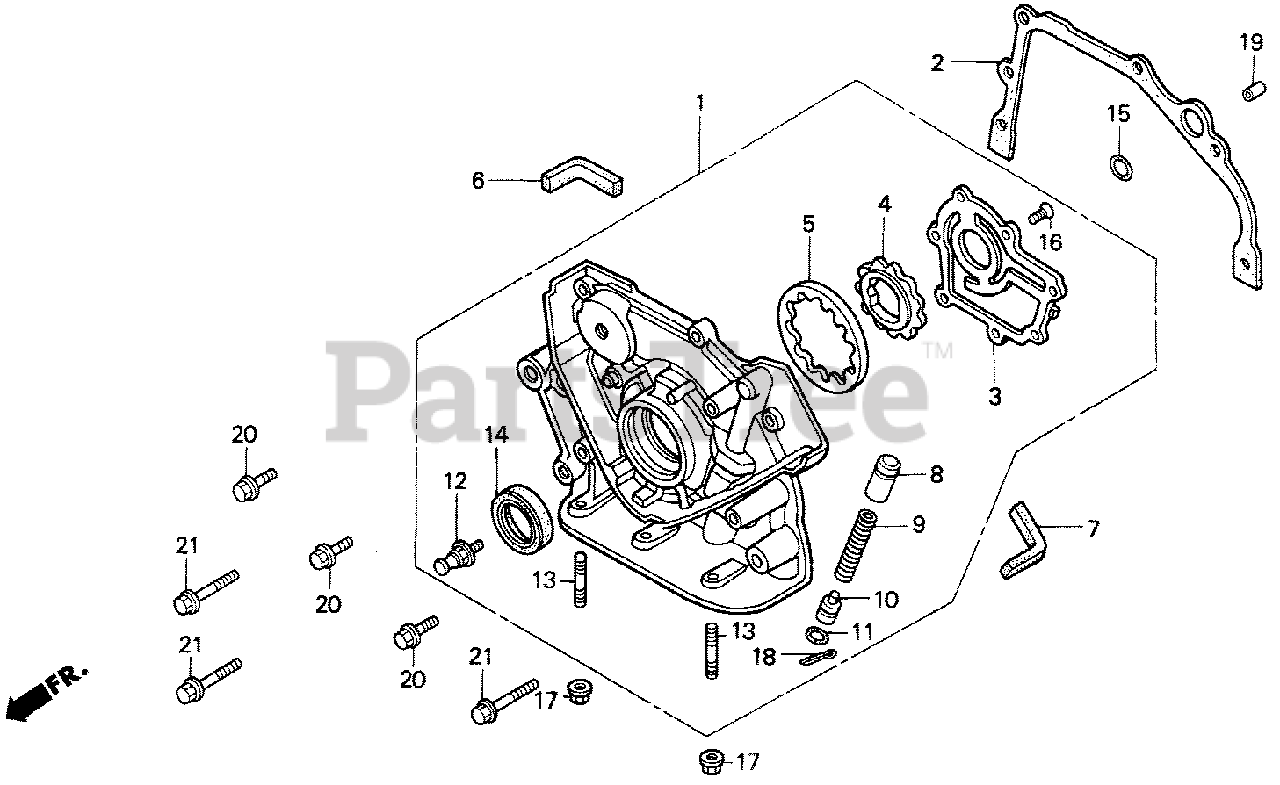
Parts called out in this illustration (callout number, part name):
1	PUMP ASSY., OIL
2	GASKET, OIL PUMP BODY (NON-ASBESTOS)
3	COVER, OIL PUMP
4	ROTOR, PUMP (INNER) (SUMITOMO)
5	ROTOR, PUMP (OUTER) (SUMITOMO)
6	SEAL, CORNER (A)
7	SEAL, CORNER (B)
8	VALVE, RELIEF
9	SPRING, RELIEF VALVE
10	SEAT, RELIEF VALVE SPRING
11	O-RING, SPRING SEAT
12	SCREW, FLANGE (5X8.5)
13	BOLT, STUD (6X28)
14	OIL SEAL (30X45X7)
15	O-RING (17.0X2.5) (ARAI)
16	SCREW, FLAT (6X16)
17	NUT, FLANGE (6MM)
18	PIN, COTTER (3.0X45)
19	PIN, DOWEL (10X12)
20	BOLT, FLANGE (8X25)
21	BOLT, FLANGE (8X35)
